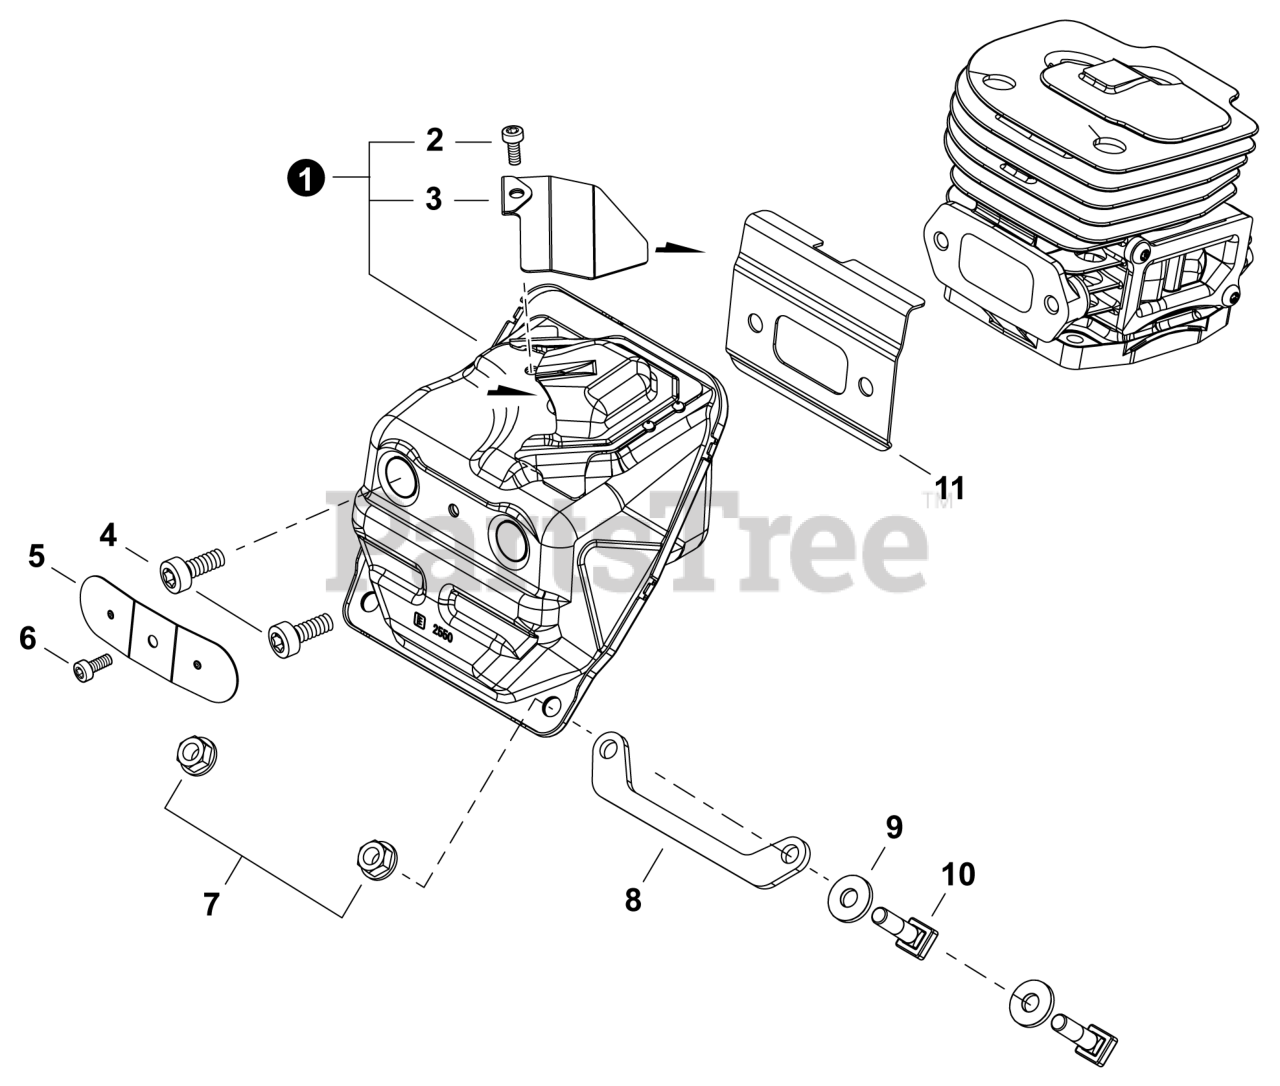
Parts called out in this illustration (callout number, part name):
1	MUFFLER ASSY
2	BOLT, TORX 4x8
3	SCREEN, SPARK ARRESTER
4	BOLT, TORX 6x20
5	PLATE, MUFFLER
6	BOLT, TORX 4x8
7	NUT, FLANGE M6x1
8	PLATE, EYE
9	WASHER 6
11	GASKET, EXHAUST
